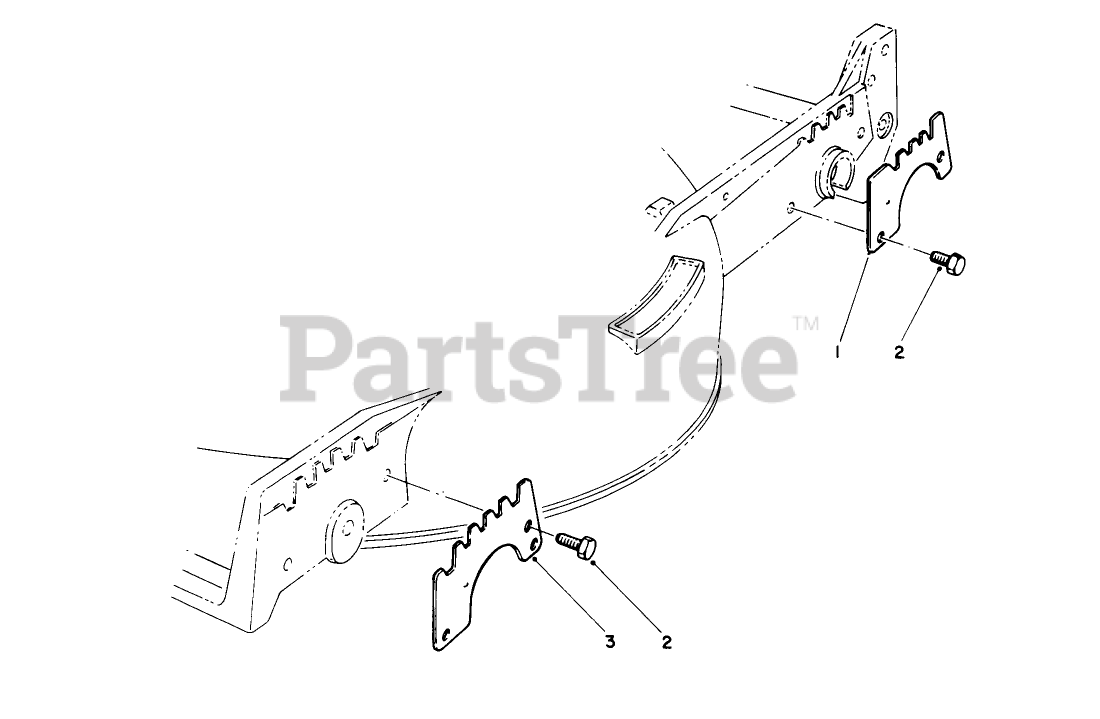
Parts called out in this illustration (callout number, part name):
1	WEAR PLATE,REAR
2	SCREW-HWH
3	WEAR PLATE
